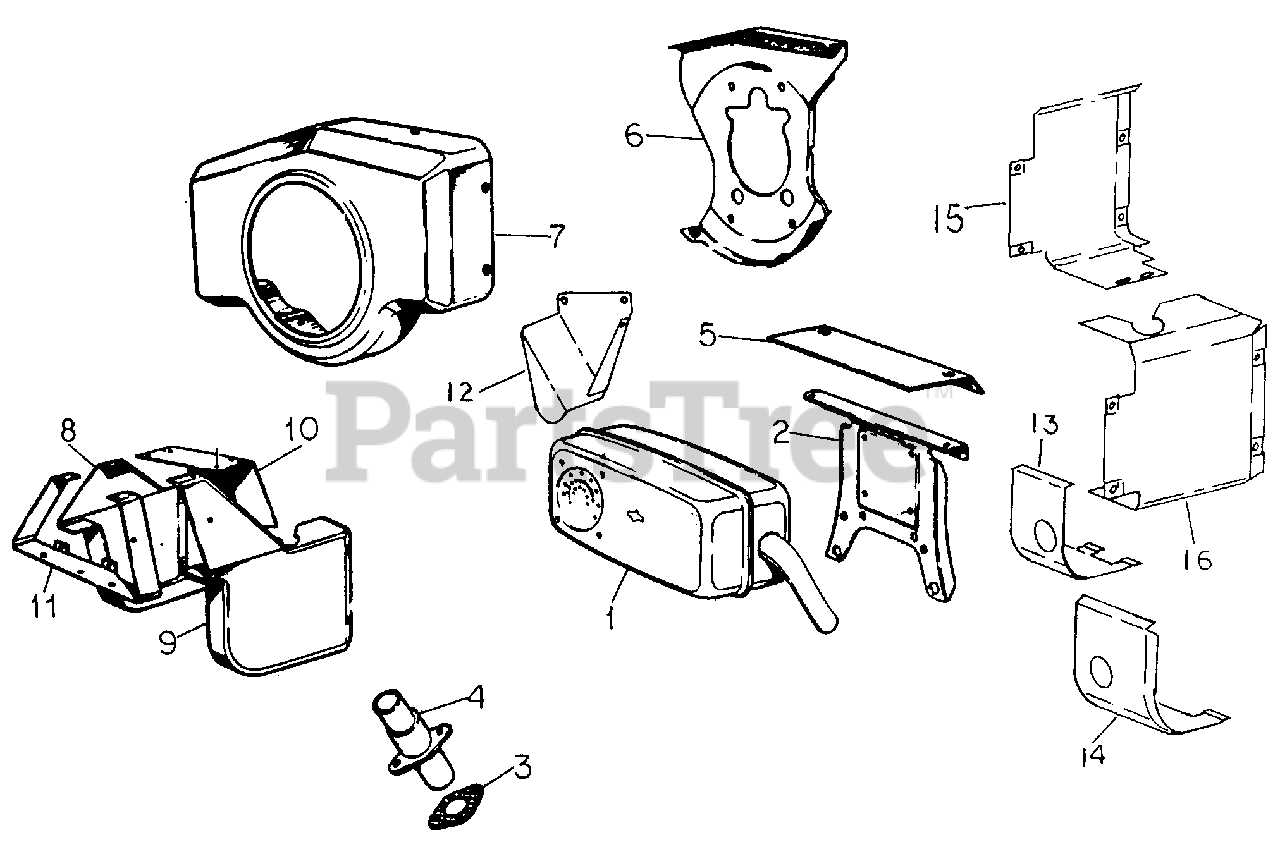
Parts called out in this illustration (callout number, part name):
1	Muffler, Exhaust
2	Bracket, Muffler Mounting
3	Gasket, Exhaust Pipe
4	Pipe Assy, Exhaust
5	Shield, Heat
6	Plate Assy, Back
7	Housing, Blower
8	Cover Assy, Shroud
9	Cover Assy, Shroud
10	Cover, Rear Insert
11	Frame, Shroud
12	Guard, Ring Gear
13	Shield, Cylinder, RH
14	Shield, Cylinder, LH
15	Cover, Air Guide, RH
16	Cover, Air Guide, LH
